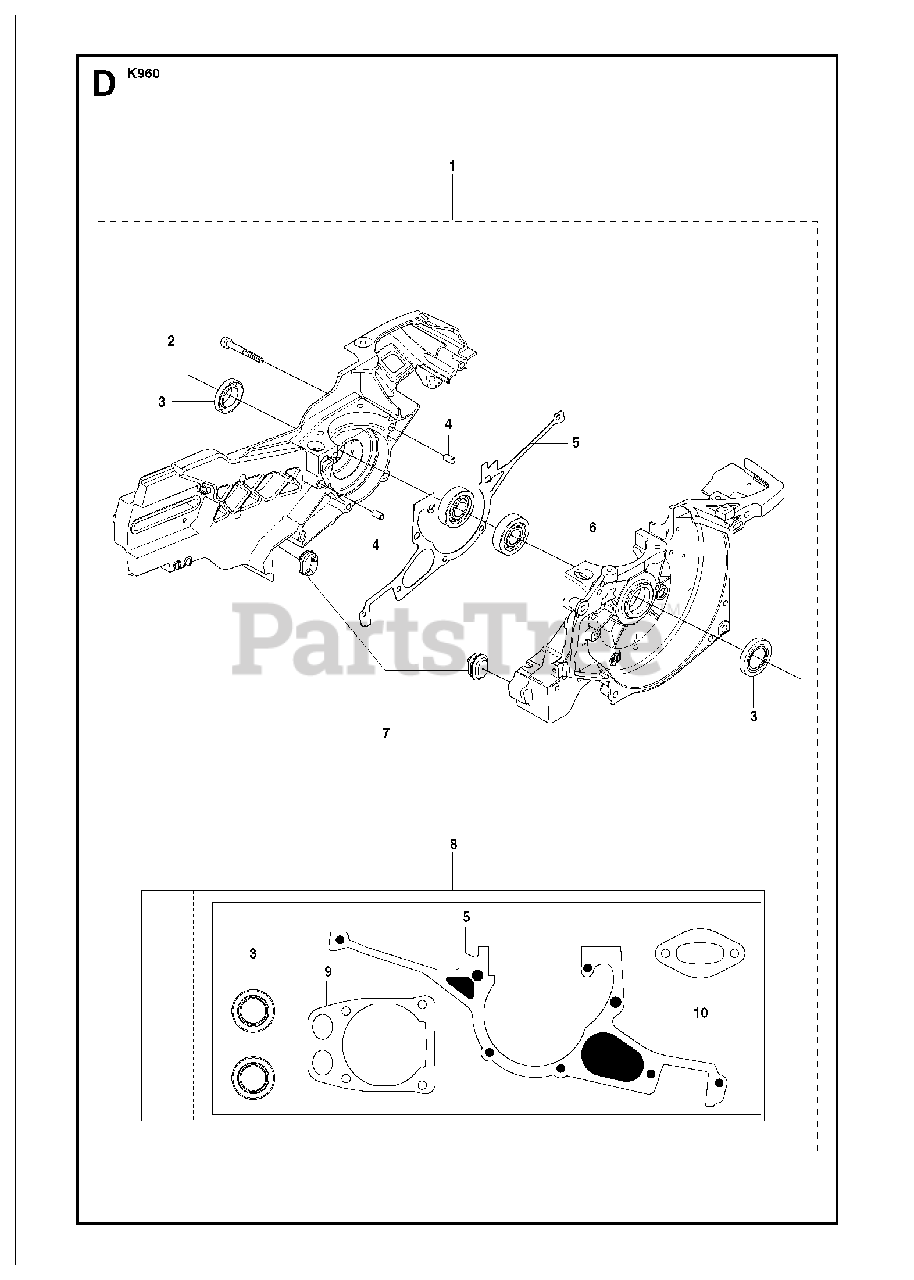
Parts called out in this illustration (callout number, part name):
1	CRANKCASE ASSYIncl. 2 - 8
2	SCREW ITXSCM
3	SEALING RING
4	GUIDE BUSHING
5	GASKET
6	BALL BEARING
7	RUBBER BUSHING
8	GASKET KITIncl. 3, 5, 9, 10
9	GASKET
10	GASKET
